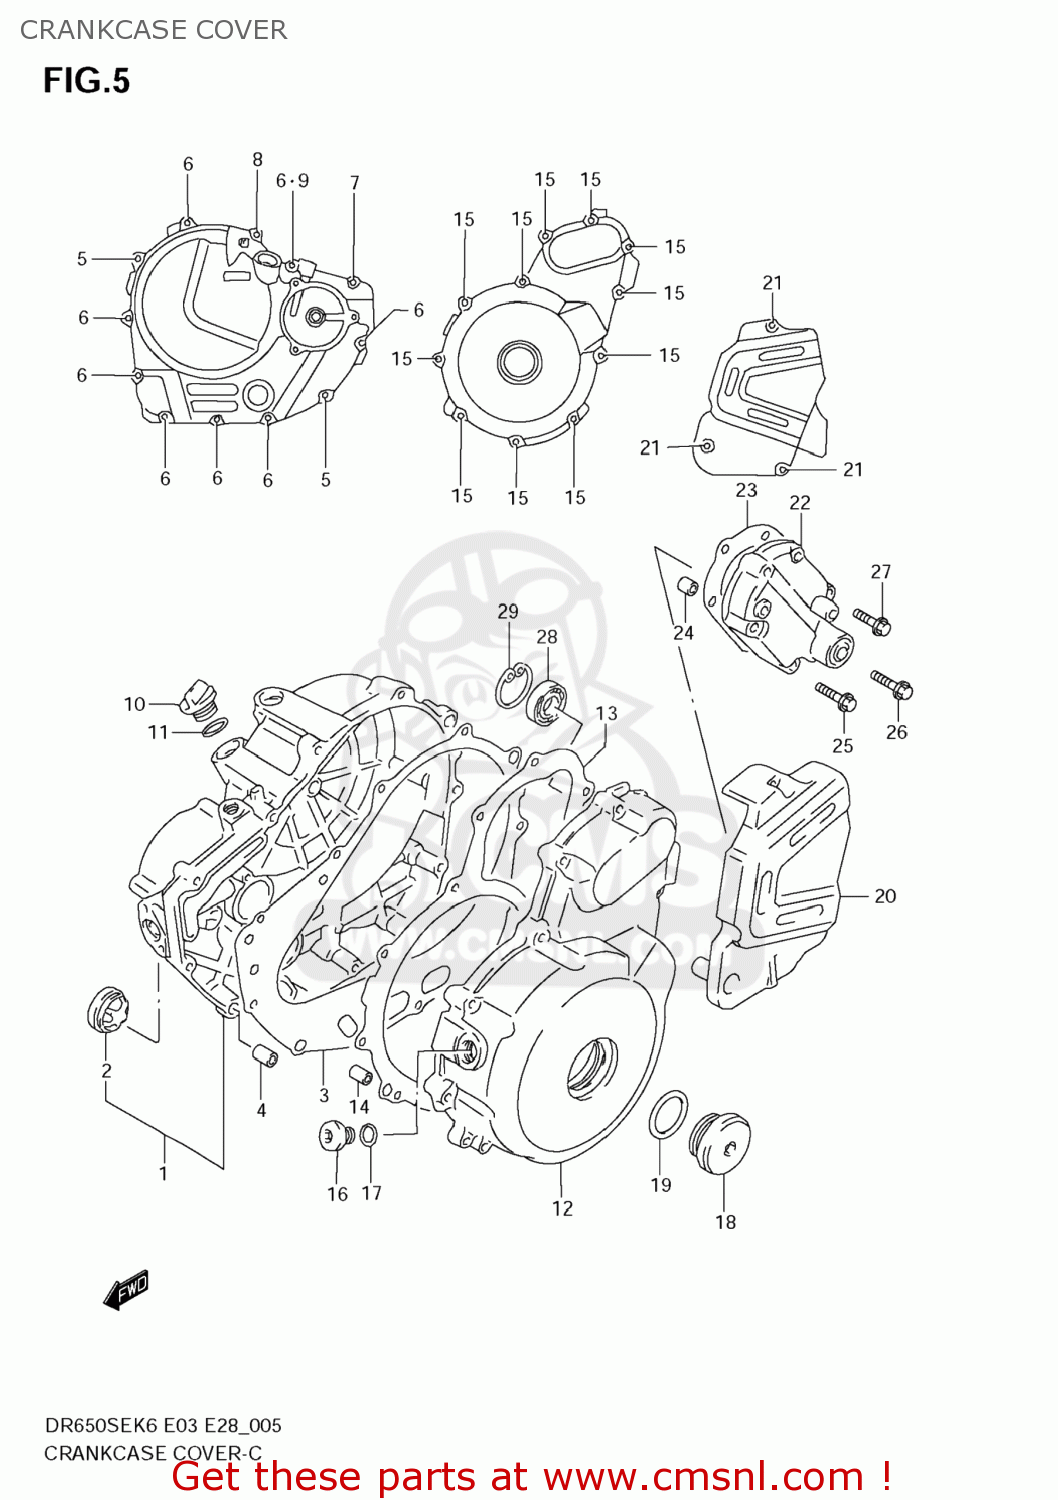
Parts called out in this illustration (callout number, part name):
1	COVER,CLUTCH
2	LENS,OIL LEVEL CHECK
3	GASKET,CLUTCH COVER
4	PIN
5	BOLT(6X45)
6	BOLT(6X35)
7	BOLT(6X30)
8	BOLT(6X25)
9	GASKET(5.8X13X1.2) (NAS)
10	PLUG
11	O RING(D:3.1,ID:16.8)
12	COVER,MAGNETO
13	GASKET,MAGNETO COVER
14	PIN
15	BOLT(6X30)
16	PLUG,14X12
17	GASKET(13.8X18.8X4.8) (NAS)
18	PLUG(SILVER)
19	O RING(D:3.1,ID:32.7)
20	COVER,ENGINE SPROCKET
21	BOLT(6X35)
22	COVER,GEAR SHIFT
23	GASKET,GEAR SHIFT COVER (NAS)
24	PIN
25	BOLT
26	BOLT
27	BOLT
28	BEARING(12X28X8)
29	CIRCLIP
